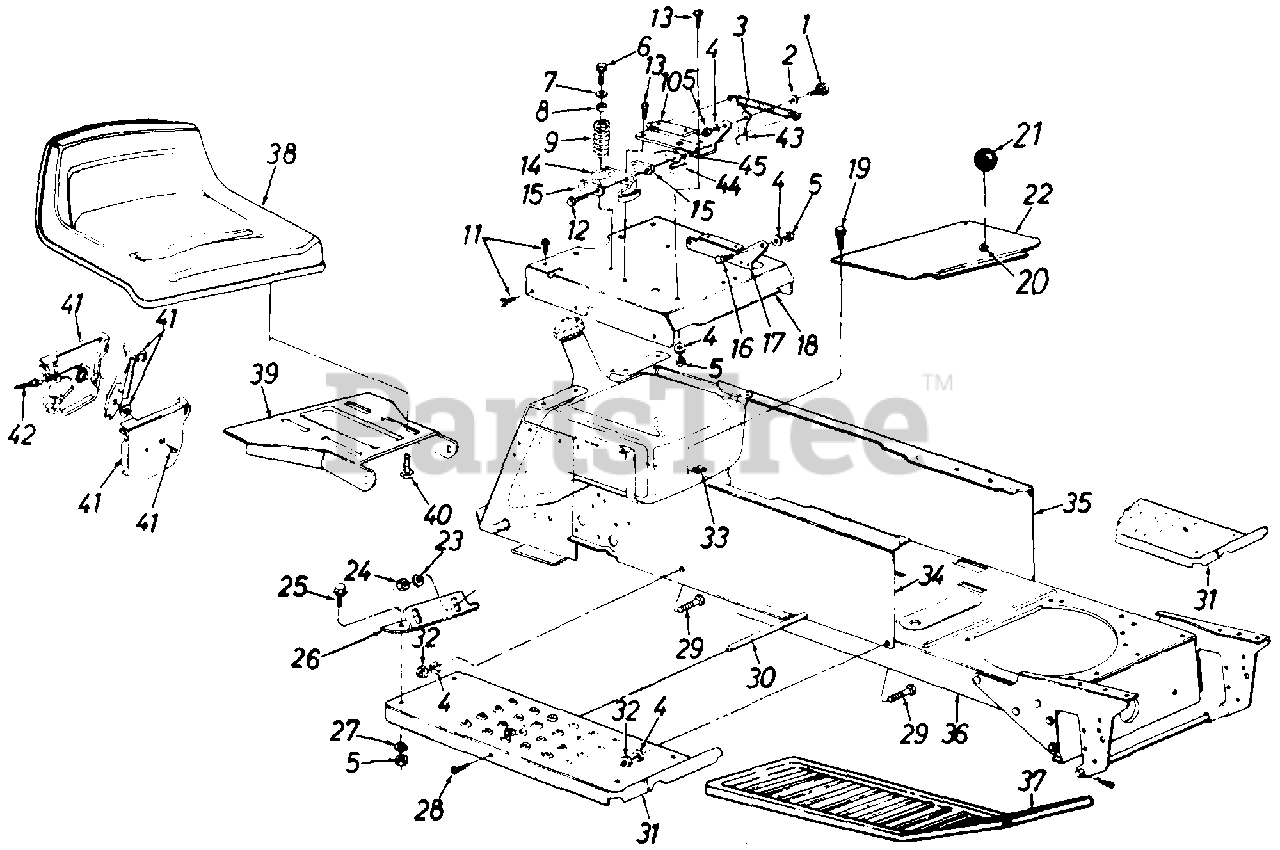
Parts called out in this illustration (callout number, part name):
1	Shld. Bolt .437" Dia. x .162"
2	Spr. Wash. .445" I.D.
3	Ext. Spring 5.31" Lg.
4	L-Wash. 5/16" I.D.
5	Hex Nut 5/16-18 Thd.
6	Hex Wash. Hd. Tap Scr. 5/16-18 x .7" Lg.
7	Fl-Wash. .344" I.D.
8	Bushing
9	Compression Spring
12	Hex Wash. Hd. AB-Tap Scr. #8 x .5" Lg.
13	Torx Md. AB-Tap Scr. 5/16-18 x .75" Lg.
14	Spring Switch
15	Insulator Plate
16	Shld. Bolt .437" Dia. x .162"
20	Snap Bushing
21	Ball Knob
22	Shift Cover
23	L-Wash. 1/4" I.D.
24	Hex Nut 1/4-20
25	Hex Bolt 5/16-18 x .75" Lg.
28	Truss Mach. Scr. 5/16-18 x .75" Lg.
29	Rib Neck Bolt 5/16-24 x .75" Lg.
30	Running Board Rod
33	Speed Nut #10Z
34	R.H. Side Frame
37	Rubber Foot Pad
38	Seat Ass'y.
39	Seat Pivot Bracket
40	Hex Tap Scr. 3/8-16 x .75" Lg.
41	Throttle Control Box Ass'y.
42	Throttle Control Wire 35" Lg.
43	Seat Lift Bracket
44	Seat Spring Switch
45	Insulator Boss Plate
